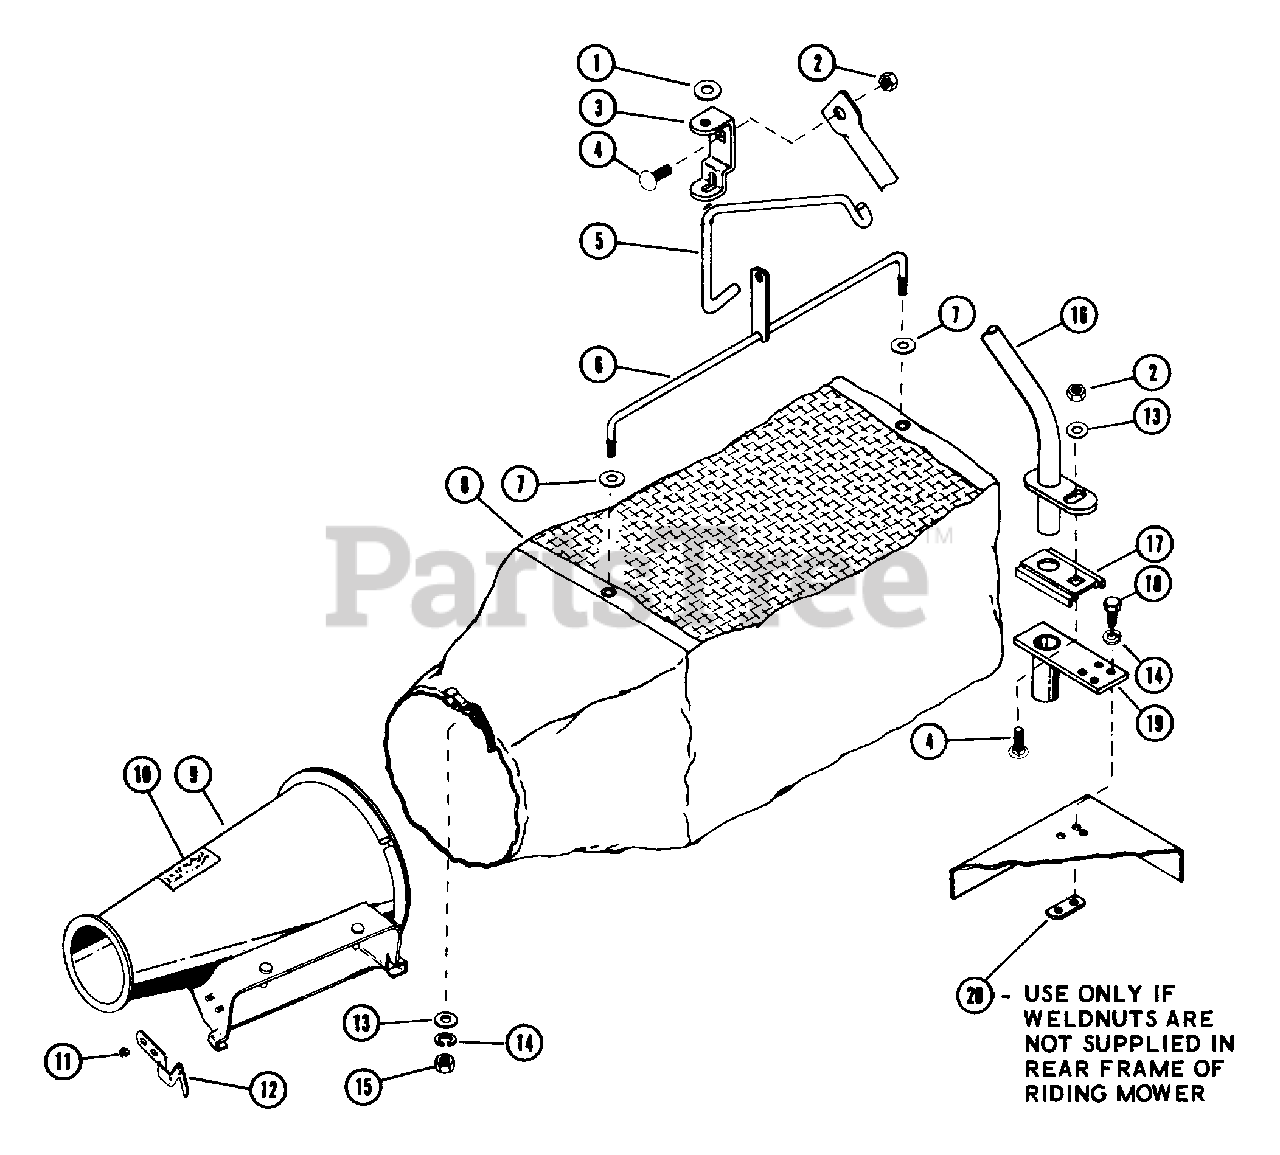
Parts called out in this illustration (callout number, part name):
1	WSHR-FL-STL .323X.625X.062 PL
2	NUT-LK-CTR .375-16 GR A PL
3	STABILIZER BRACKET
4	BLT-RDHDSQNK .38-16X.75 SHT PL
5	STABILIZER ROD
6	CROSS BAR
7	WSHR-FL-STL .38X.875X.083 PL
8	BAG
9	30 IN CONE
10	CAUTION LABEL
11	NUT-LK-FLG .250-20 PL
12	SPRING, FLAT
13	WSHR-FL-STL.406X.812X.065PL
14	WSHR-LK .375X.115 HVY PL
15	NUT-HEX .375-16
16	SUPPORT BAR
17	CHANNEL BRACKET
18	BLT-HEX .38-16X.75 PL GR2
19	BAR BRCKT
20	BRACKET
